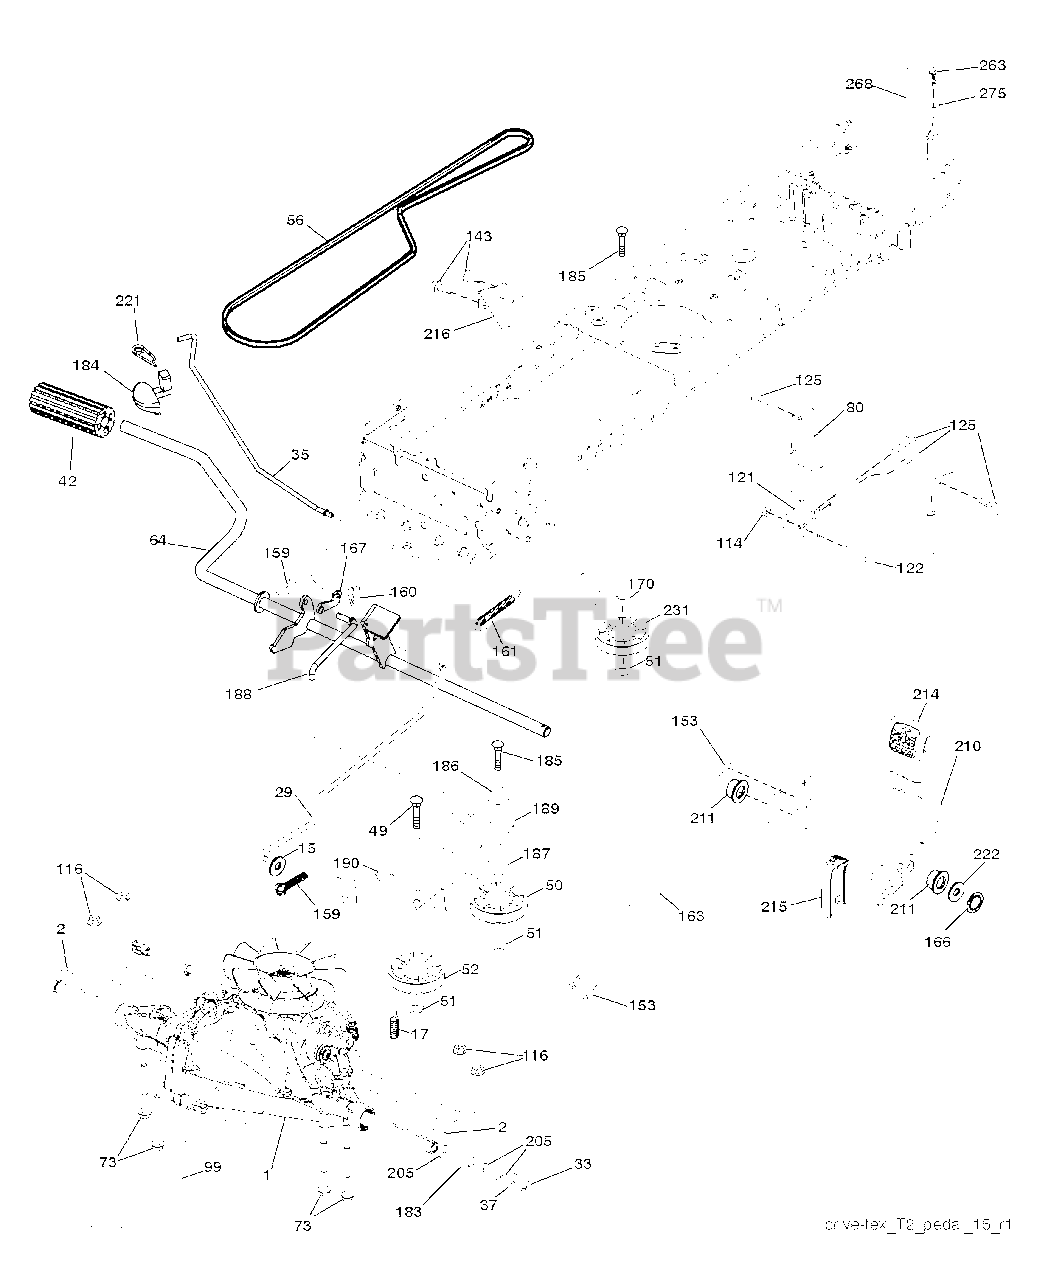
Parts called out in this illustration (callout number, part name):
2	SQUARE KEY
15	WASHER
17	SPRING.BRAKE.HG3000/3500
29	ROD.BRAKE.T2.TEX
35	ROD.CNTRL.PARK.PREDATOR.LT.TEX
42	PEDAL COVER T
50	IDLER.FLAT.910.OFFSET
51	NUT LOCK FLG 3/8-16 UNC
52	IDLER.V-GROOVE.910.OFFSET
64	SHAFT.ASM.PEDAL.BRK.CNTR
73	BOLT HEX 5/16-18 GR 5
80	STRAP.TORQUE.T2
99	ROD.ASM.BYPASS.SPRING.T2.FS
114	NUT.71038.31-18.HEX.NYLOCK
116	NUT LOCK HEX FLANGE 5/16-18
121	BRACKET STRAP TORQUE
122	BOLT.5/16-18X2.5
125	SCREW
143	SCREW LT
153	RETAINER M
159	COTTER PIN
160	RETAINER CLIP
161	SPRING, RETURN LT
163	ROD.CONTROL.PCH.T2.TEX
166	NUT.PUSH.625
167	LATCH.BRAKE.SPRING
170	KEEPER.CENTER SPAN.1.688
183	SPACER, AXLE PVST
184	HANDLE.PARKNG BRK.PRED.LT.428
186	SPACER.RETAINER
187	WASHER 12/32X2X10GA
188	RP LINK.CLUTCH.GROUND.DRIVE
189	BELLCRANK.GROUND.DRIVE.TEX.
190	KEEPER.BELLCRANK.DRIVE
210	ROCKER.ASM.PEDAL.CONTR
211	BEARING.NYLON
214	PEDAL.FORWARD.PAD.TEX
215	PEDAL RUBBER REVERSE
216	BRACKET.PULLEY.IDLER.W/TEX
221	RETAINER.SPRING.CLIP.H
222	WASHER 21/32 X 1-1/4 X 10 GA.
231	IDLER.V-GROOVE.1.688.OFFSET
263	SCREW, 3/8-16X3/4
268	GUARD MUFFLER
275	WASHER
